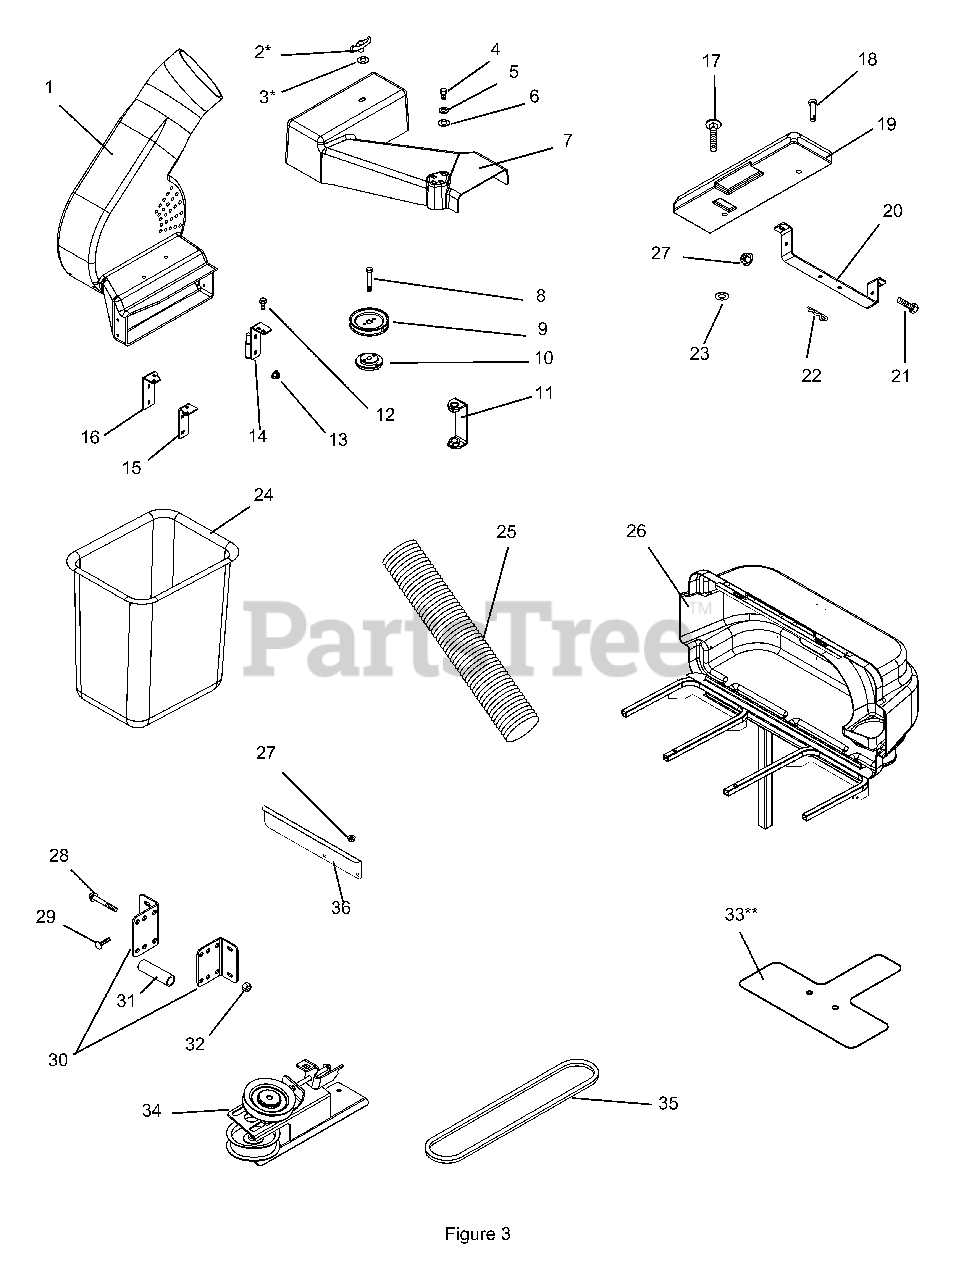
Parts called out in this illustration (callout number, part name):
1	BLOWER (SERVICE ASSEMBLY)
2	KNOB - WING .312-18 UNC
3	WSHR-FL-STL .380X1.50X.062 YWZ
4	@BLT-HEX .38-16X.75 GR5 YWZC
5	@WSHR-LK .38X.094 REG YWZC
6	@WSHR-FL-STL.438X1.00X.083 YWZ
7	BELT COVER W/DECAL
8	BLT-HEX .38-16X1.75 GR8 M-EPYZ
9	SHEAVE, 3.00 DIA.
9	SHEAVE, 4.00 DIA.
10	ASSEMBLY, SHEAVE ADAPTER
11	SPACER, COVER
12	@BLT-HEX .25-20X.75 GR5 YWZC
13	@NUT-LK-TOP-FLG .25-20 YWZC
14	WELDMENT, REAR MOUNT BRACKET
15	BRACKET, FRONT
16	WELDMENT, FRONT MOUNT BRACKET
17	@BLT-RDHDSQNK .38-16X1.00 G5YZ
18	PIN-CLEV .494X2.50 BRIGHT ZINC
19	WEIGHT, CAST IRON
20	BRACKET,WEIGHT
21	@BLT-HEX .38-16X1.00 GR5 YWZC
22	PIN-HAIR-EXT .12X.31X2.37 YWZC
23	WSHR-FL-STL .515X1.625X.250 YZ
24	GRASS BAGGER BASKET
25	HOSE,7X45 KANAFLEX 165CL
26	Cover Assembly
27	@NUT-LK-TOP-FLG .38-16 YWZC
28	@BLT-HEX .50-13X3.00 GR5 YWZC
29	@BLT-RDHDSQNK .38-16X1.25 G5YZ
30	BKT,BAGGER MOUNT
31	SPACER, PIVOT .500X.750X1.805
32	@NUT-LK-TOP-FLG .50-13 YWZC
33	GUARD,FINGER
34	Idler Assembly
35	V-BELT, HA-WRAPPED
35	V-BELT, HA-RAW EDGE
36	DEFLECTOR, EXHAUST
